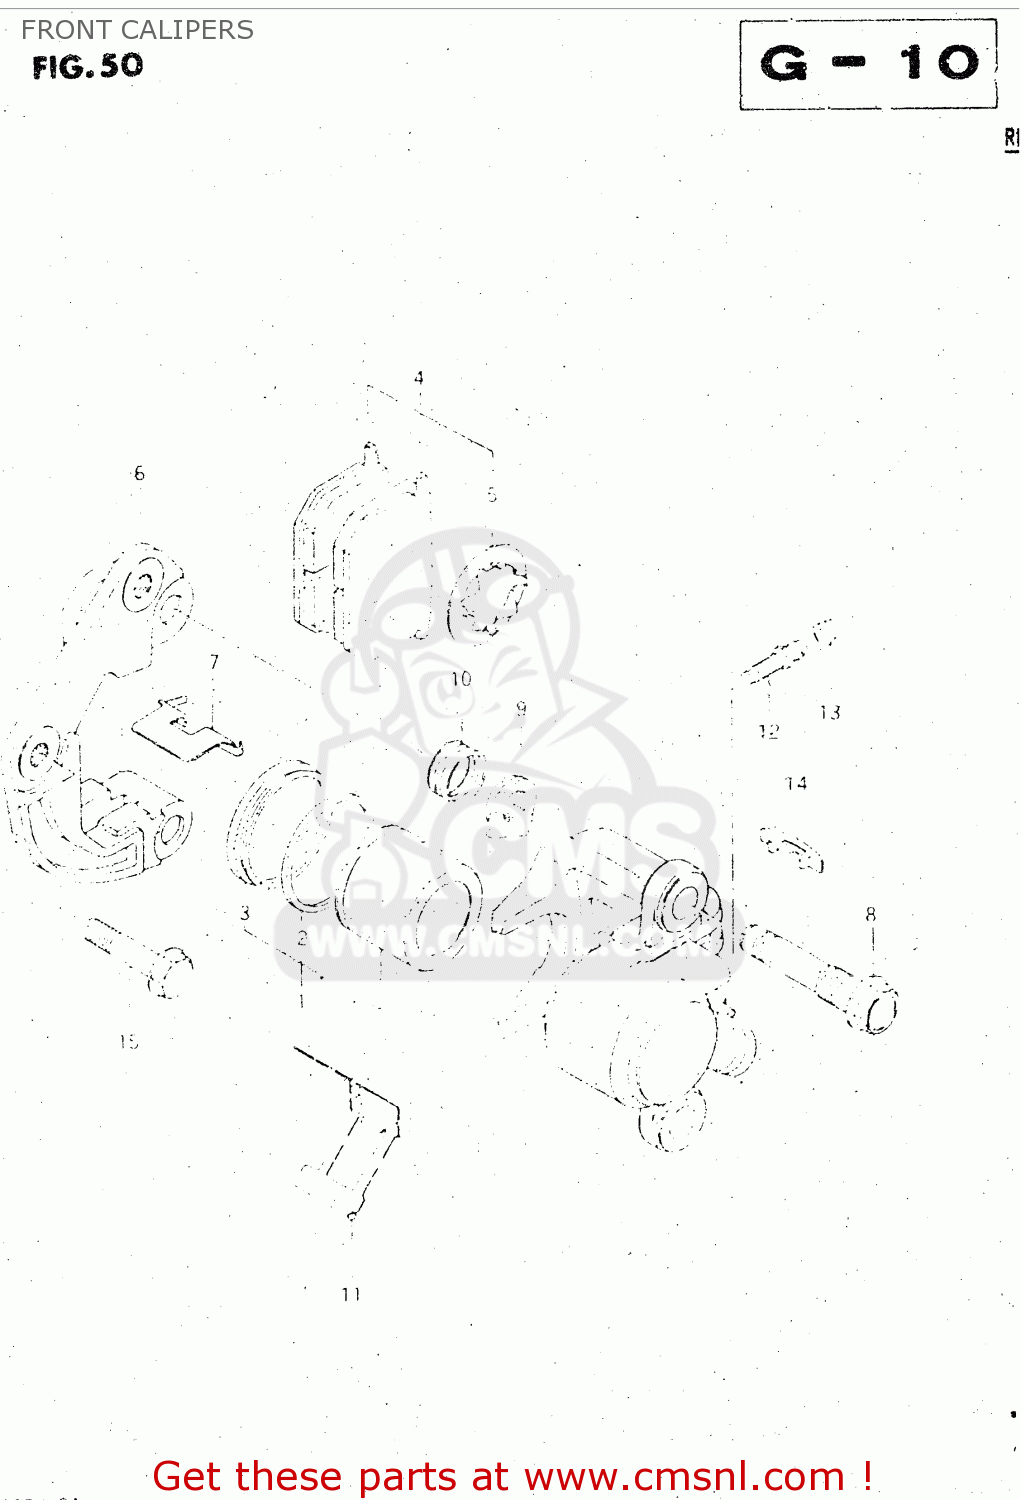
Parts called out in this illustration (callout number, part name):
1	PISTON SET
2	SEAL,PISTON
3	BOOT,PISTON
4	PAD & SHIM SET (MCA)
5	SHIM,PAD
6	HOLDER,CALIPER,LEFT
7	PAD,GUIDE
8	AXLE,CALIPER
9	NUT,CALIPER AXLE
10	BOOT
11	SPRING
12	BREATHER
13	CAP,BLEEDER PL
14	COVER,INDICATOR
15	BOLT(10X37)
